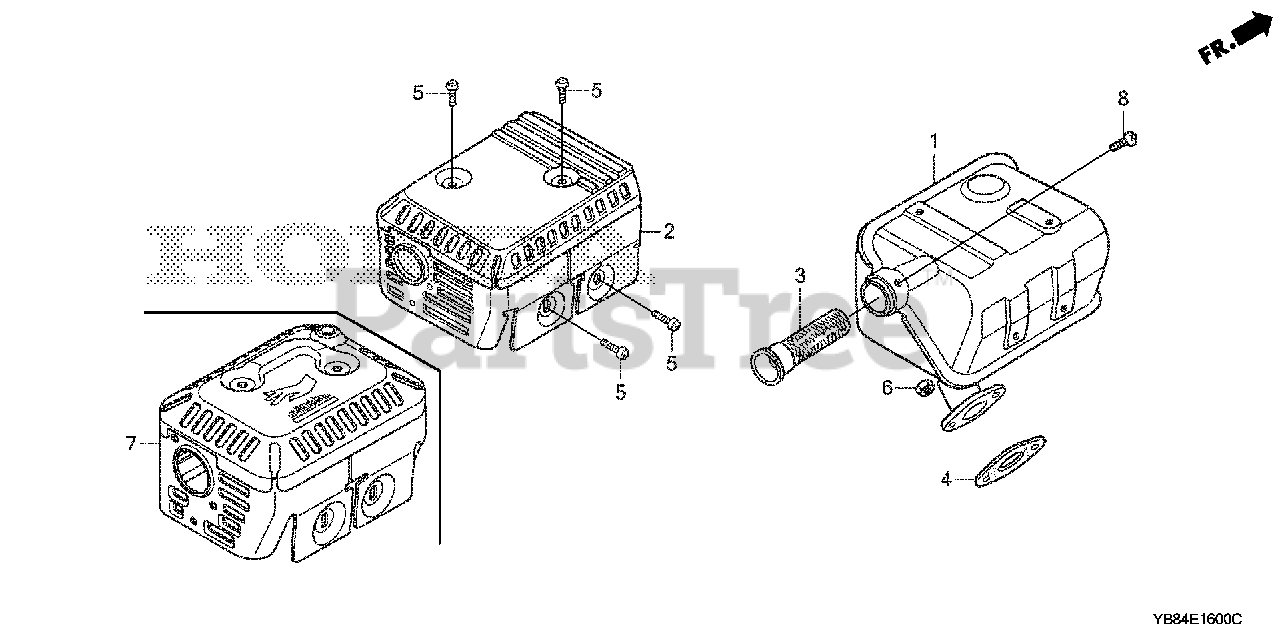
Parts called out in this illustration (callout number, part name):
1	MUFFLER
1	MUFFLER (ARRESTER)
3	ARRESTER, SPARK
4	GASKET, MUFFLER
5	SCREW, TAPPING (5X8)
6	NUT, HEX. (8MM)
7	PROTECTOR, MUFFLER (STD)
8	SCREW, TAPPING (4X6) (TO INSTALL OPTIONAL SPARK ARRESTER)
